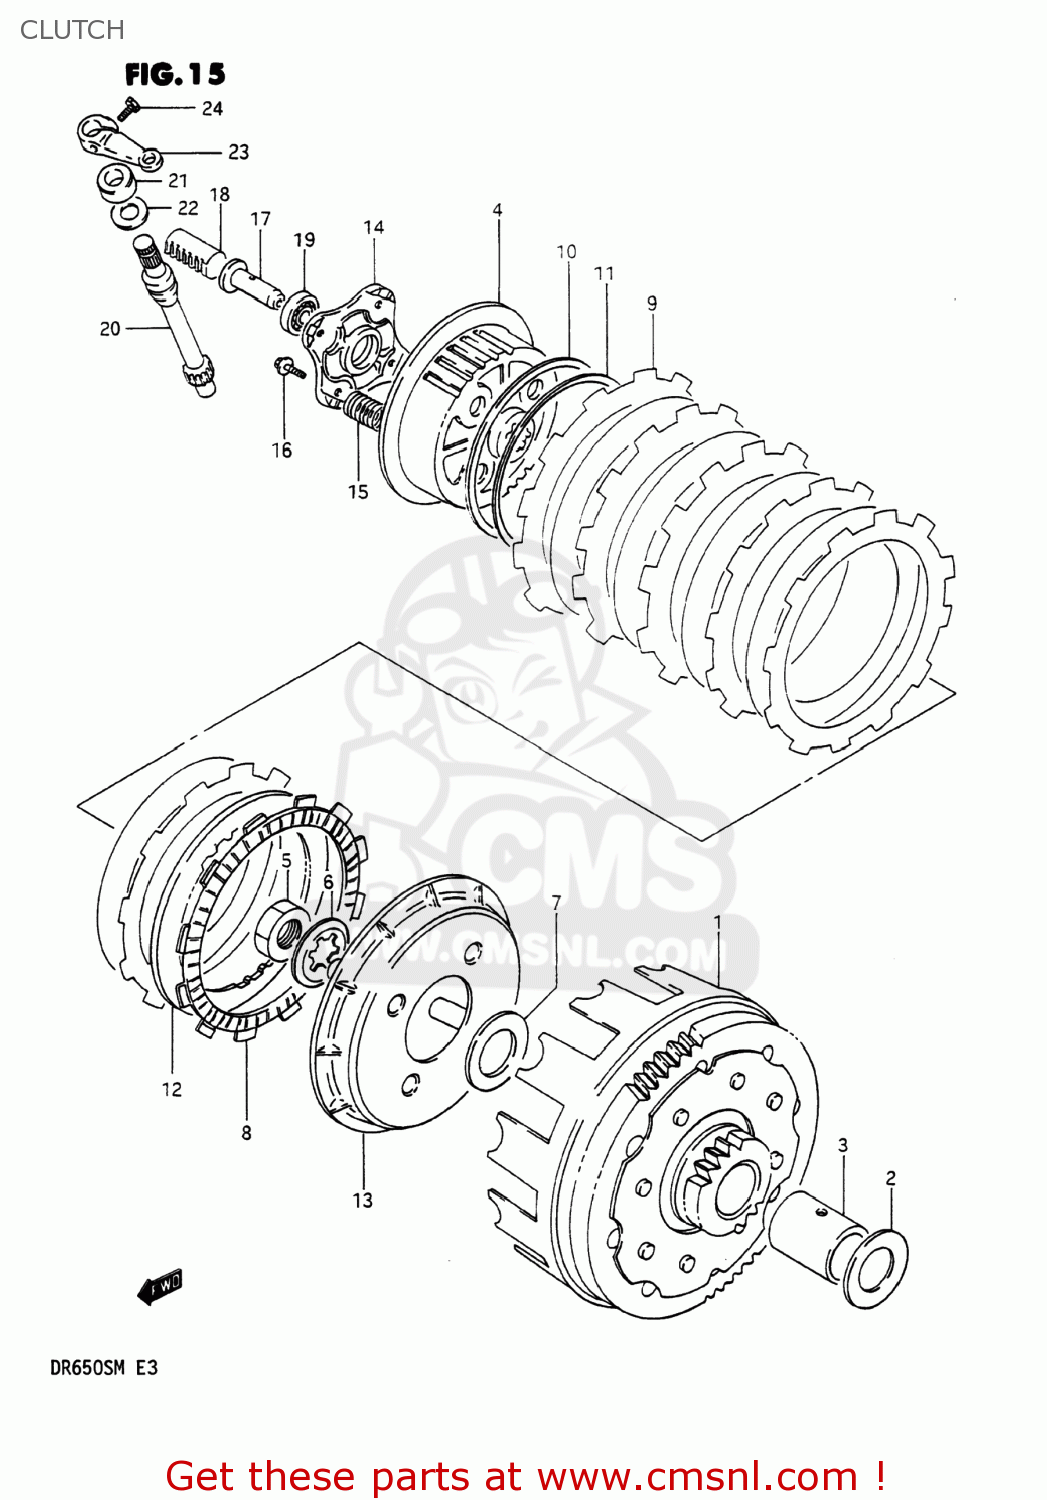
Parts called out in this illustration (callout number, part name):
1	GEAR ASSEMBLY,PRIMARY DRIVE
2	WASHER
3	SPACER(22X28X32.5)
4	HUB,CLUTCH SLEEVE
5	NUT
6	WASHER,LOCK
7	WASHER
8	PLATE,CLUTCH DRIVE (NAS)
9	PLATE,CLUTCH DRIVE NO (NAS)
10	SEAT,WAVE WASHER(T:1.4)
11	WASHER
12	PLATE,CLUTCH DRIVEN (NAS)
13	DISC,CLUTCH PRESSURE
14	PLATE,RELEASE
15	SPRING
16	BOLT 6X20
17	PIECE,CLUTCH PUSH
18	RACK,CLUTCH RELEASE
19	BEARING
20	PINION,CLUTCH RELEASE
21	SEAL,OIL (12X22X9)
22	WASHER (14.2X22X1)
23	ARM,CLUTCH RELEASE
24	BOLT
